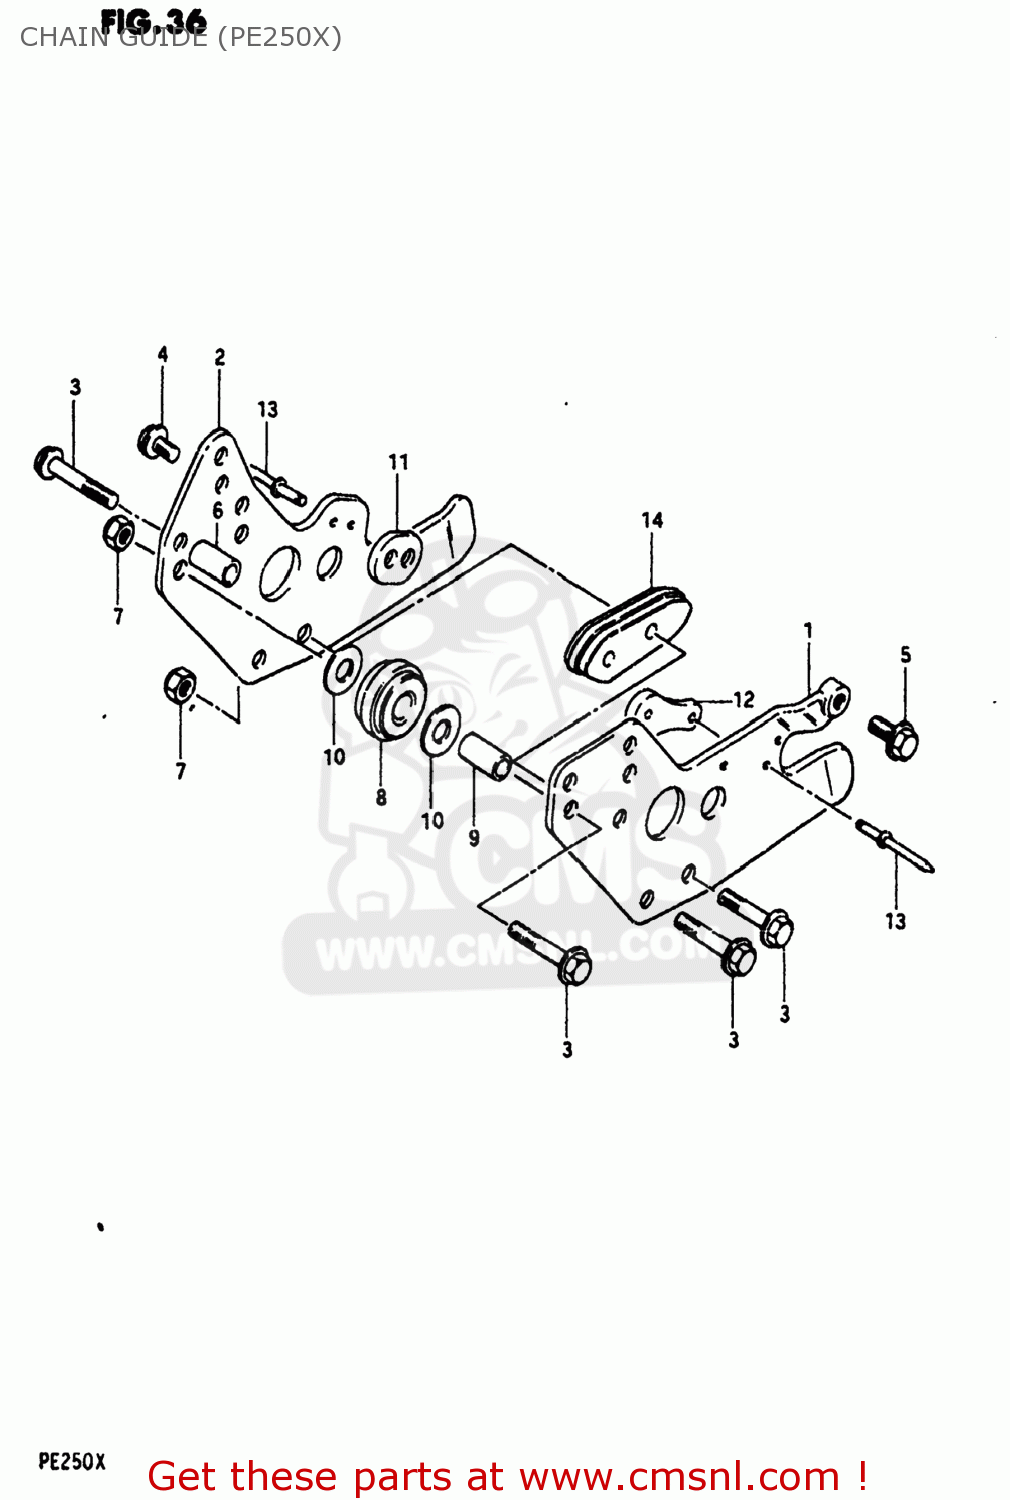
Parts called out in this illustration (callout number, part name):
1	PLATE,CHAIN GUIDE,OUTER
2	PLATE,GUIDE CHAIN
3	BOLT
4	BOLT
5	BOLT
6	SPACER(6.8X10X24.2)
7	NUT
8	ROLLER,CHAIN GUIDE
9	SPACER,CHAIN GUIDE ROLLER
10	WASHER
11	PAD,DRIVE CHAIN GUIDE
12	PAD,DRIVE CHAIN GUIDE
13	RIVET
14	DEFENSE,CHAIN GUIDE
